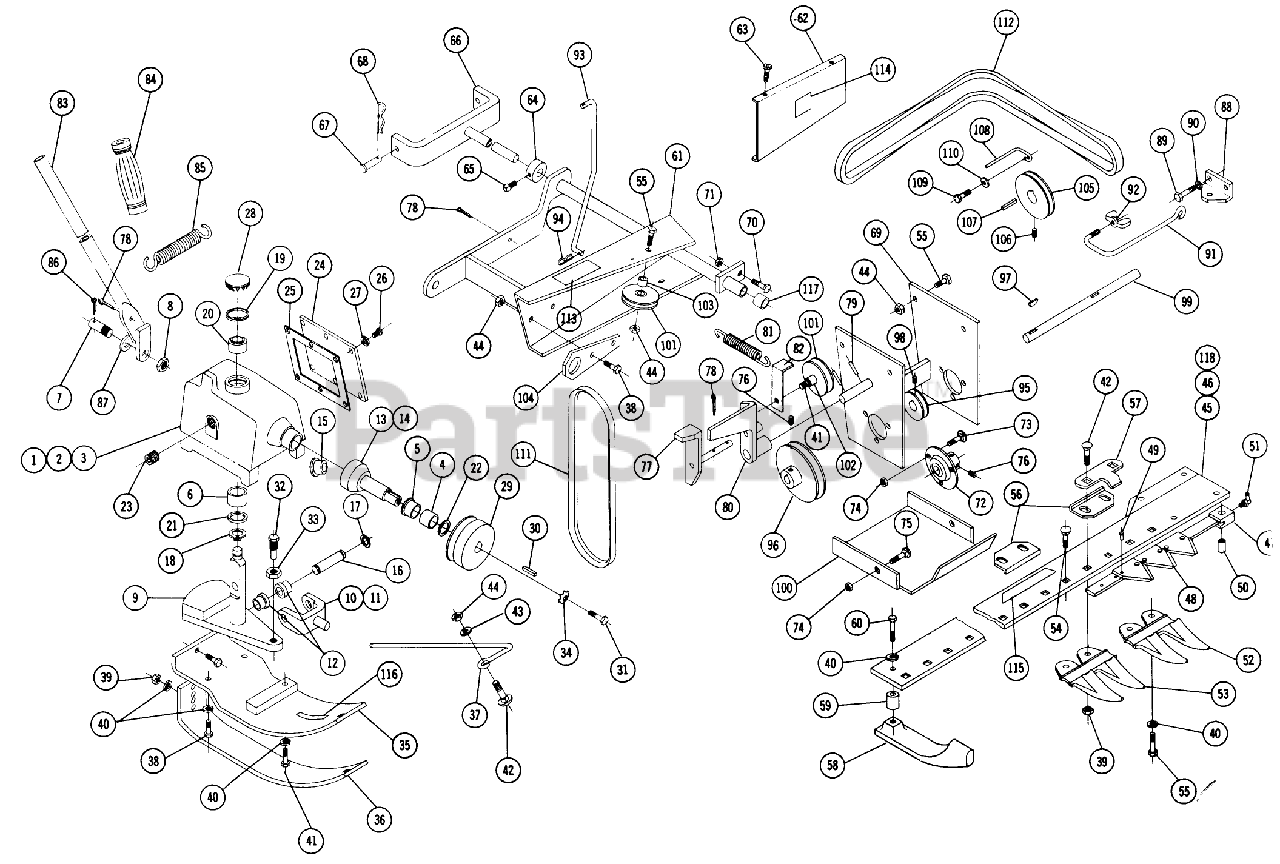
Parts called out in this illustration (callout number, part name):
1	Ass-y Housing Complete-Sickle Drive
2	Ass-y Housings Bearings
3	Housing
6	Bearing-Bronze Sleeve
7	Pin
8	Nut, 3/4-16
9	Ass-y. Shaft-Weldment
10	Ass-y. Yoke
11	Yoke
13	Ass-y. Shaft Bearing
14	Shaft
15	Bearing-Bronze Sleeve
17	SNAP RING- 5/8 EXT
19	Ring-Snap
22	OIL SEAL
24	Cover Plate
26	Screw-Rd. Hd. #10-24 x 3/8
27	Lockwasher #10
28	Plug Button
31	Bolt 3/8-16 x 7/8
32	Pin Sickle Drive
33	Nut-5/8-18
35	Ass y. Shoe-Upper-Weldment
36	Shoe-Lower
38	Bolt 3/8-16 x 1
40	Lockwasher
41	Bolt, 3/8-16 x 1/2
42	Bolt Carriage 3/8-16 x 1
43	Washer
44	3/8-16 E.S.
45	Ass-y. Cutter Bar Complete
46	Ass-y. Bar Guard
48	Section
49	Rivet
50	Bushing
54	Bolt 3/8-16 x 1
55	Bolt 3/8-16 x 1
56	Wear Plates
60	Bolt, 3/8 16 x 2
62	Cover Belt
63	Screw Hex Self Tap #8-32 x 3/8
66	Ass-y. Bracket Rod
68	Hairpin
71	Locknut-1/2-13
73	Bolt Hex 5/16-18 x 3/4
74	Nut-Nylok
75	Bolt-Car. 5/16-18 x 1
76	Set Screw
77	Ass-y. Lever
78	Cotter Pin
79	Roll Pin
80	Pedal
81	SPRING *R
83	Ass-y. Lever Lift
86	Cotter Pin 3/16 x 1
87	Washer
88	Bracket-Travel Hook
89	Bolt 5/16-18 x
90	Lockwasher
92	3/8 NC Wing Nut
94	Hairpin
96	Pulley
97	Key
98	Set Screw Nylok
99	Shaft
100	Shield Pulley
103	SPACER
104	Link
106	Set Screw-1/4-20 x 1/2
108	Stop-Belt
109	Bolt, 7/16 14 x 1
110	Washer 7/16
116	Decal
118	Ass-y.-Bar Guards
